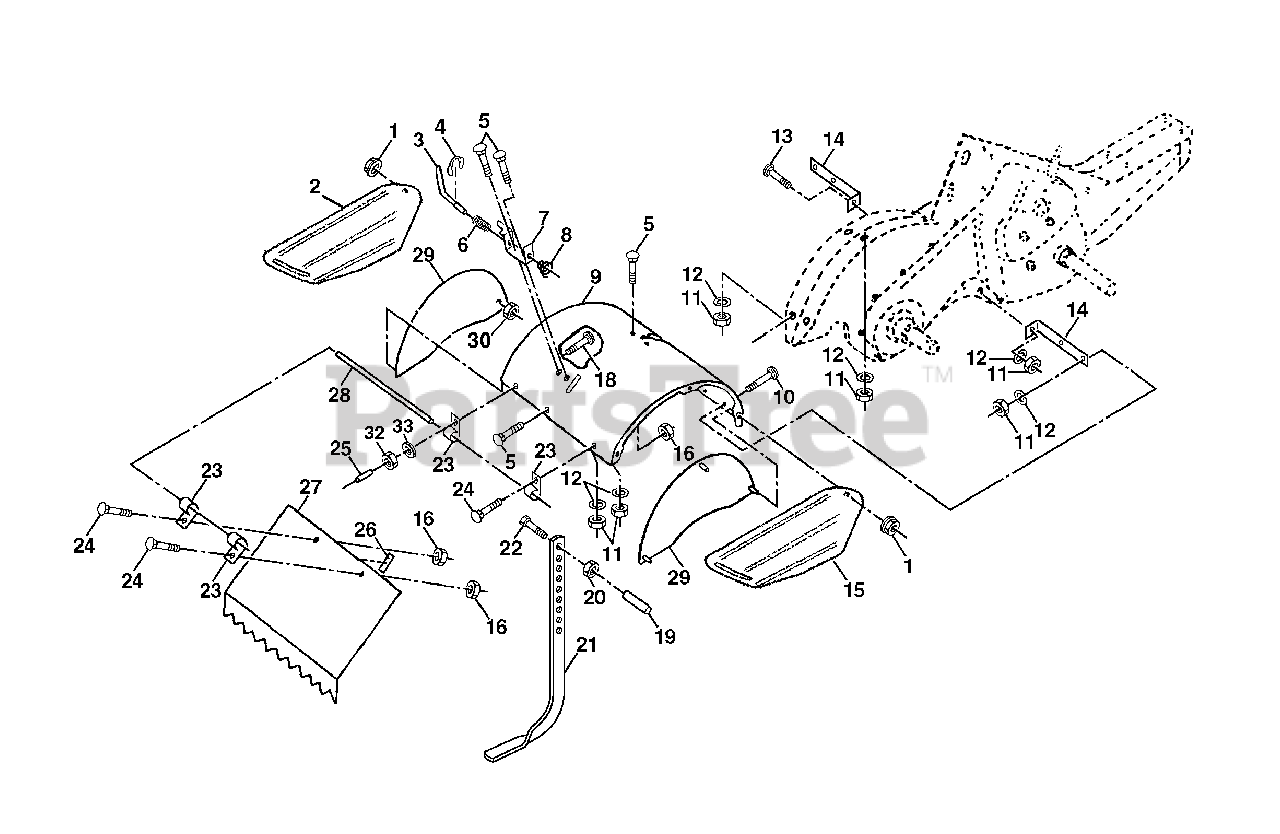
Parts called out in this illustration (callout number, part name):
1	Nut, Flange 5/16-18
2	Shield, Side, Outer L. H.
3	Pin, Stake, Depth
4	Ring, Klip
5	Bolt, Carriage 5/16-18 x 3/4 Gr 5
6	Spring
7	Bracket, Latch
8	Spring, Depth Stake
9	Shield, Tine
10	Bolt, Carriage 5/16-18 x 1
11	Nut, Hex 5/16-18
12	Washer, Lock 5/16
13	Bolt, Carriage 5/16-18 x 1-1/4
14	Bracket, Shield Tine
15	Shield, Side, Outer R.H.
16	Nut, Hex Flange 1/4-20 UNC
18	Bolt, Carriage 1/4-20 x 1-1/4 Gr. 5
19	Grip
20	Nut, Hex 3/8-16
21	Stake, Depth
22	Bolt, Hex 3/8-16 x 2
23	Hinge
24	Bolt, Carriage 1/4-20 x 1/2 Gr. 5
25	Cap, Vinyl
26	Pad, Idler
27	Shield, Leveling
28	Pin, Hinge
29	Shield, Side
32	Nut Fin Hex 1/4-20 UNC
33	Washer Lock Hvy Helical 1/4
